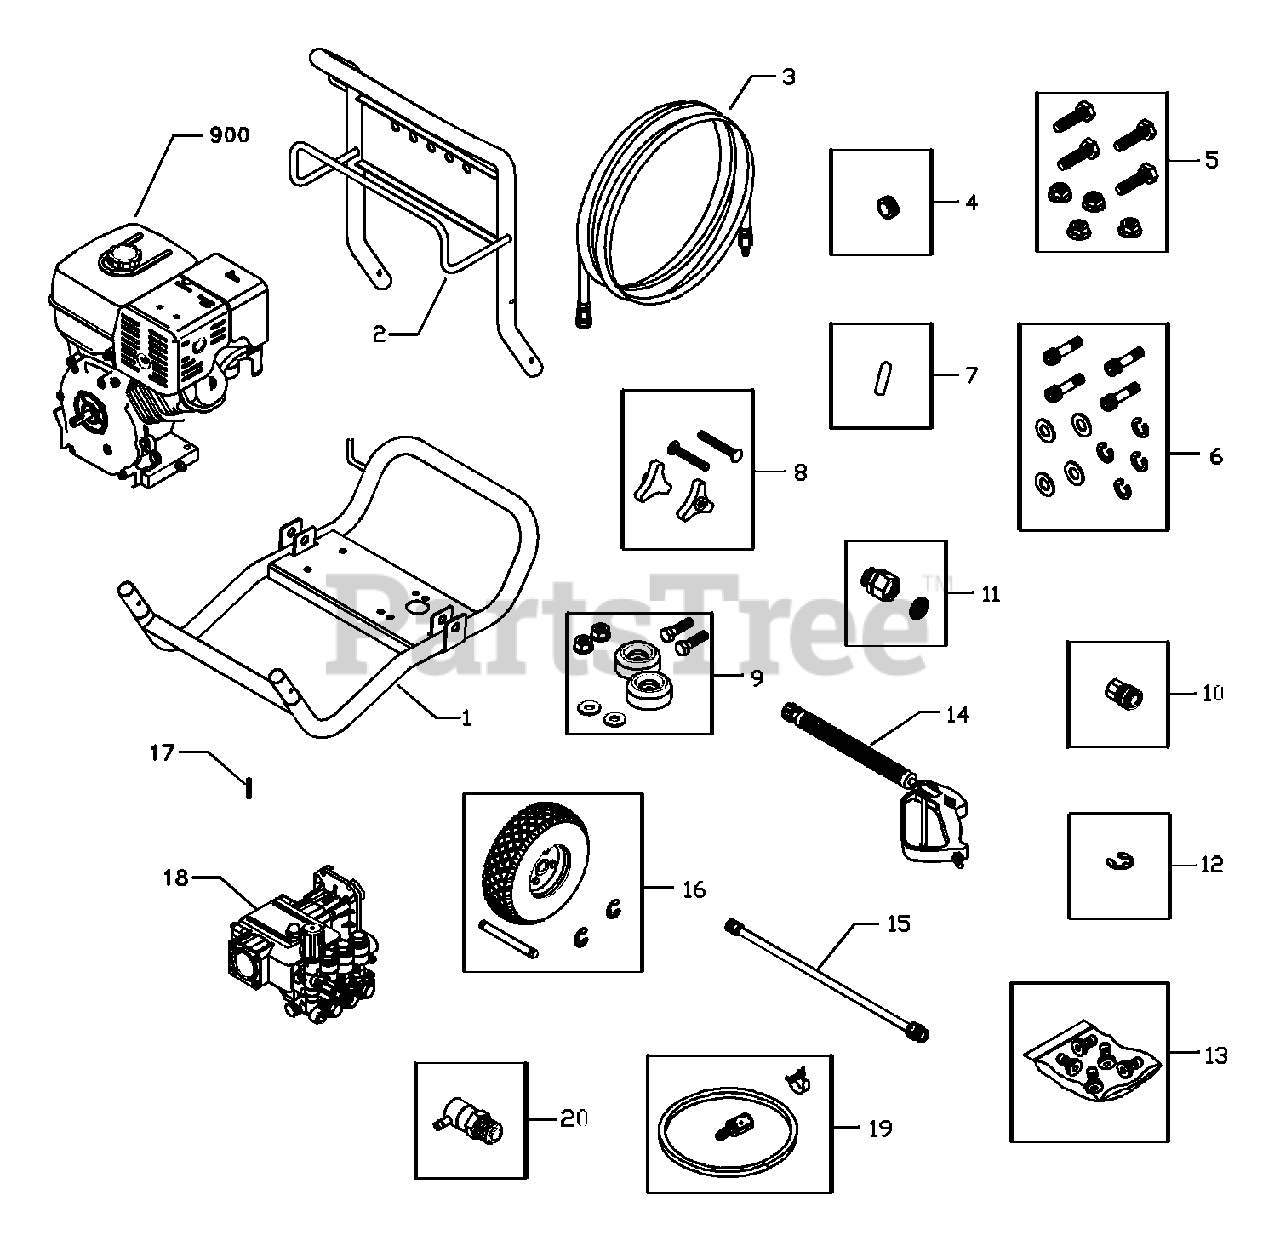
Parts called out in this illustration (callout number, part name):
5	KIT, Engine Mounting Hardware
6	KIT, Pump Mounting Hardware
7	VINYL CAP
8	KIT, Handle Fastening
9	KIT, Vibration Mount
10	QUICK CONNECT
11	KIT, Garden Hose Inlet
13	KIT, Spray Tips
15	EXTENSION
16	KIT, Wheel
18	ASSY, Pump
18	ASSY, Unloader
19	KIT, Chemical Hose/Filter
20	VALVE, Thermal Relief
